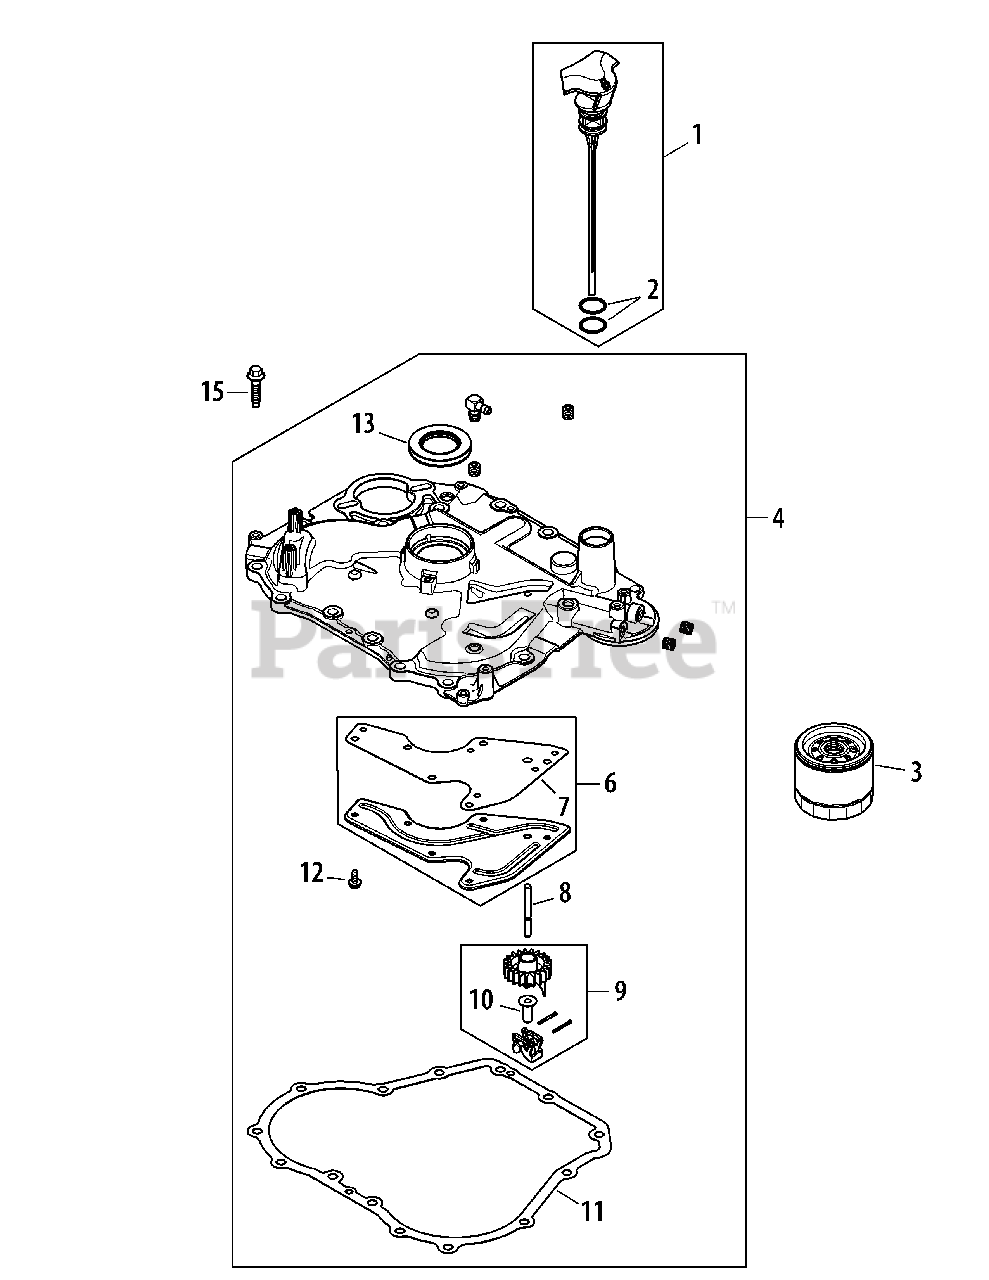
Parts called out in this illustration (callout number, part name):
1	Dipstick Ass’y-Std Yellow (Incl. 2)
4	Closure Plate Assembly (Incl. 6-13)
6	Oil Passage Cover Kit (Incl. 7)
7	Oil Passage Gasket
8	Governor Cross Shaft
9	Governor Gear Assembly
10	Governor Regulating Pin
11	Closure Plate Gasket
12	Flg. Thd. Frm. Screw, M5 X 0.8 X 13
15	Hex Flange Screw, 1/2
